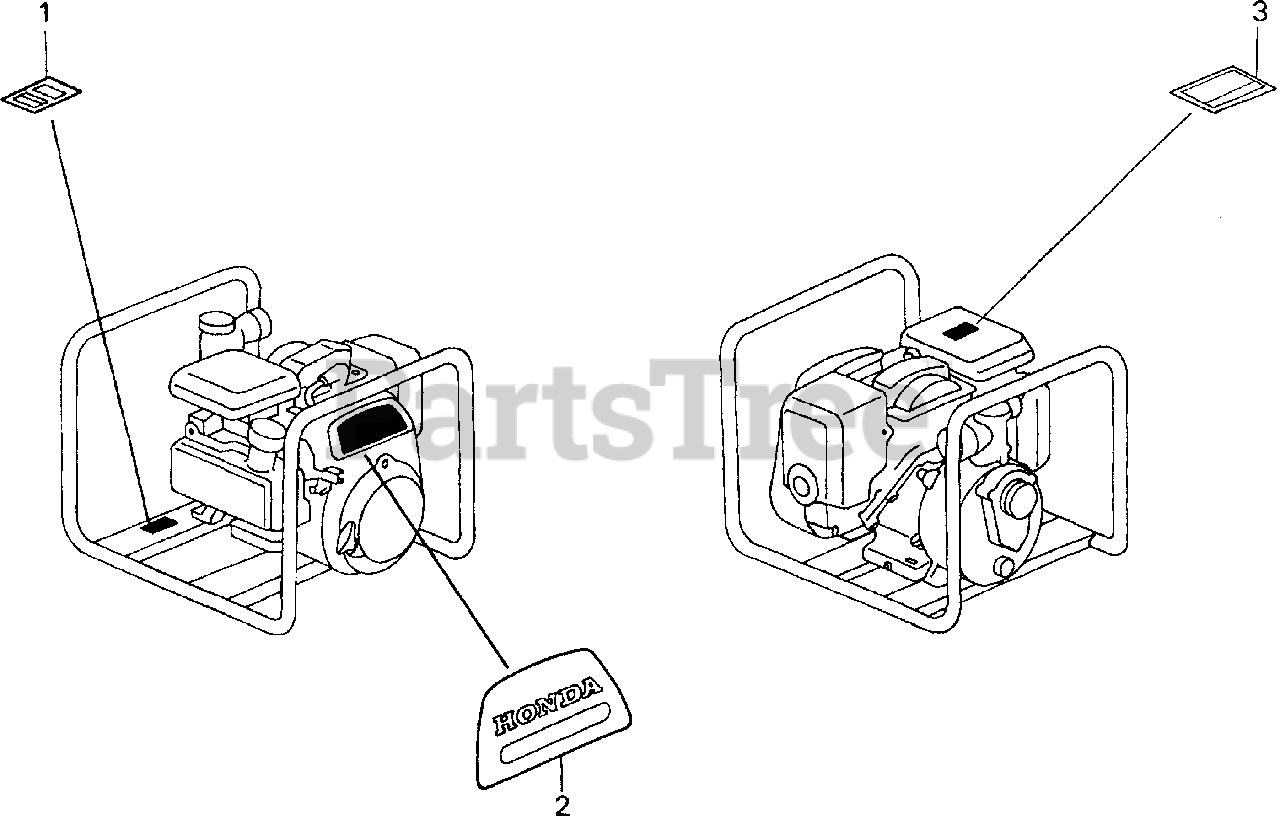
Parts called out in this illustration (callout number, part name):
1	LABEL, CAUTION (PUMP)
2	MARK, EMBLEM (WN20)
2	EMBLEM (WN20)
3	LABEL, PUMP WARNING
